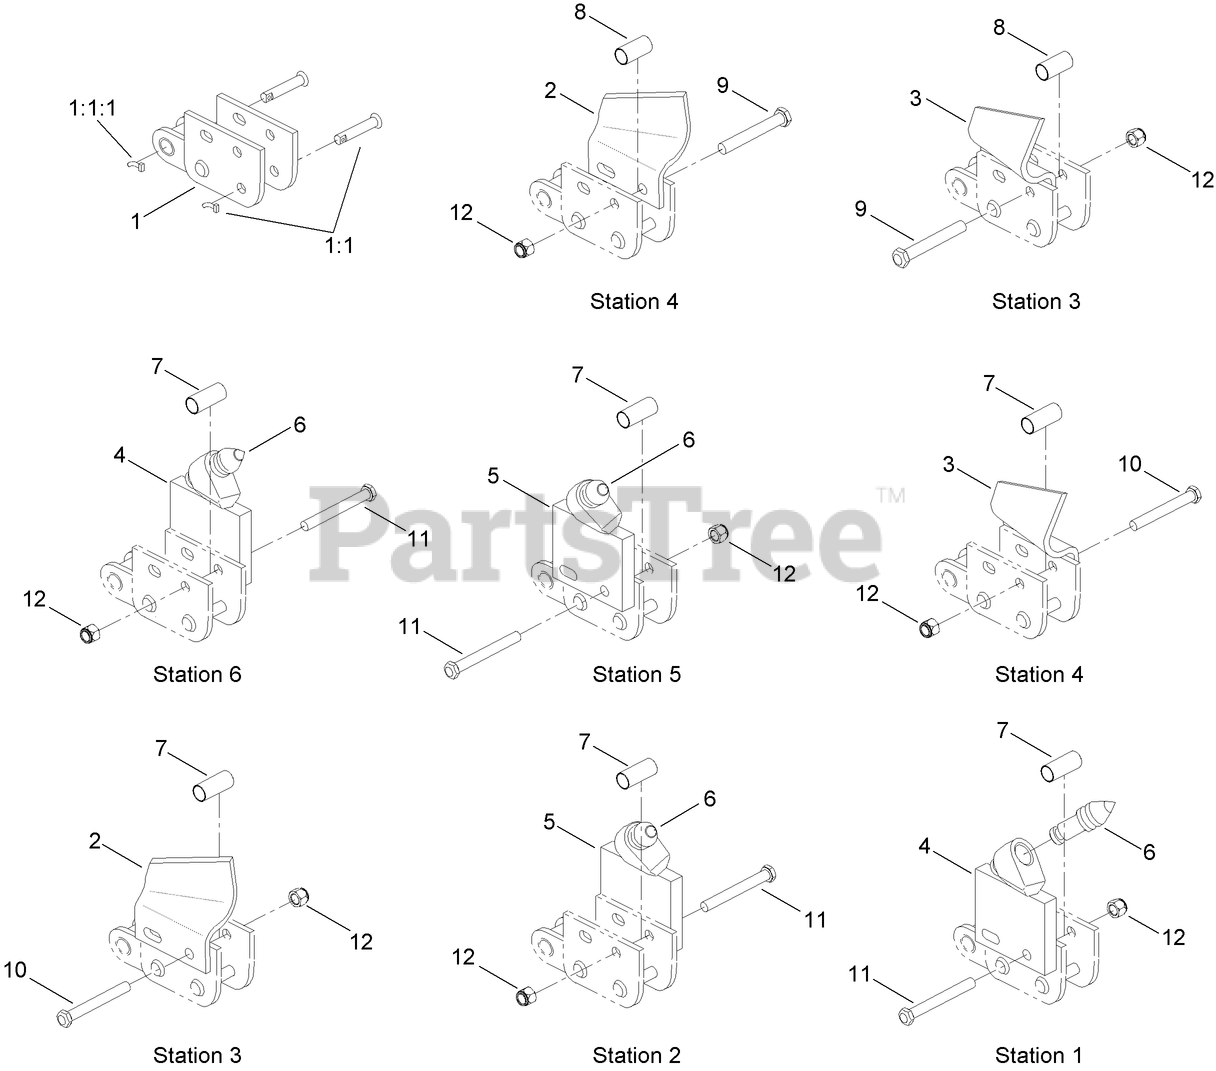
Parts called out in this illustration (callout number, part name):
1	CHAIN REPAIR LINK ASM
1:1	NOTCHED PIN AND KEEPER ASM
1:1:1	PIN-KEEPER
2	CUTTER-CUP, LH
3	CUTTER-CUP, RH
4	HOLDER-BIT, LH
5	HOLDER-BIT, RH
6	BIT AND CLIP, CARBIDE
7	SPACER-TUBE, OUTSIDE MOUNT
8	SPACER-TUBE, INSIDE CUP MOUNT
9	BOLT-HH
10	BOLT-HH
11	BOLT-HH
12	NUT-LOCK
